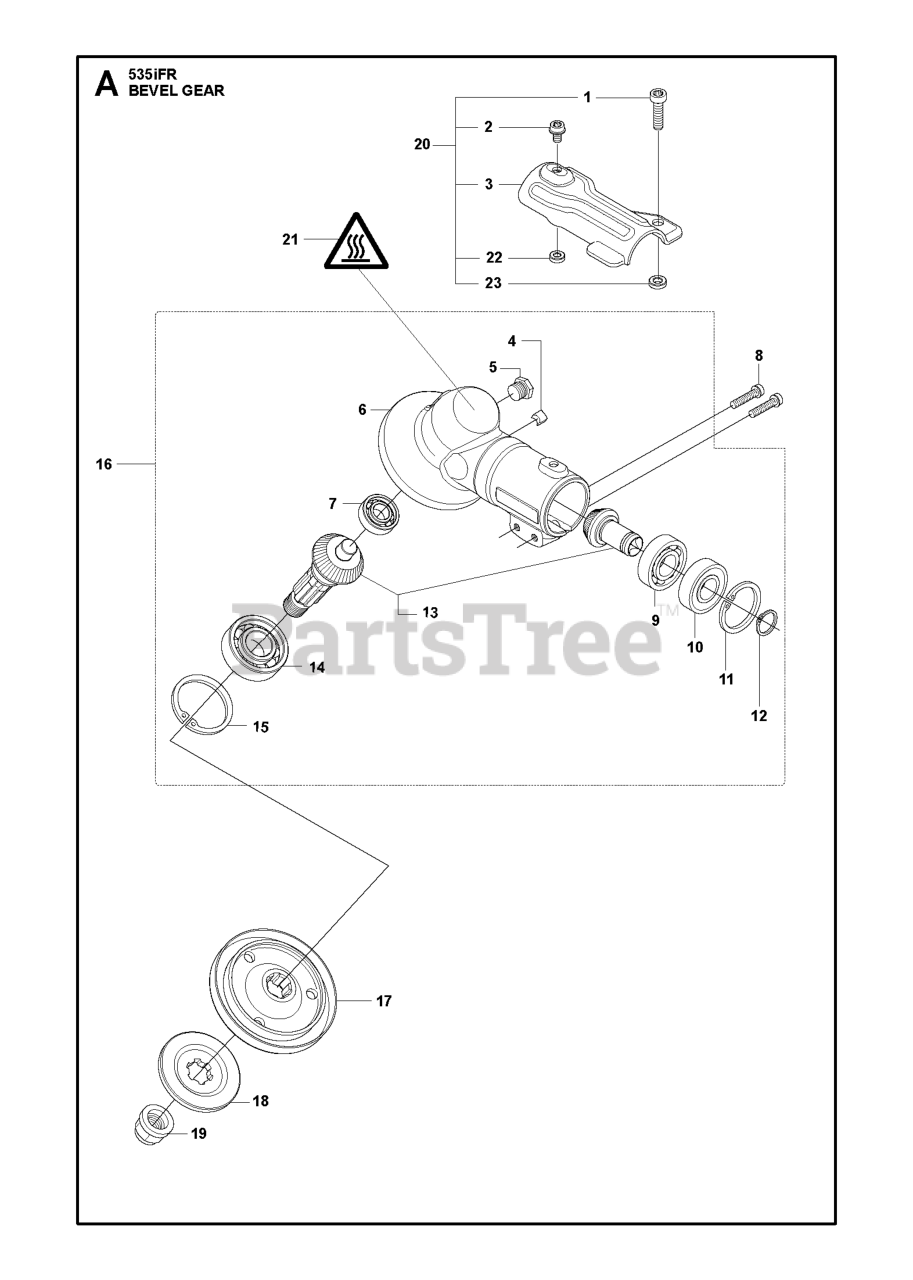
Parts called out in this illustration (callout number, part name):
3	RP HOLDER
5	PLUG
7	BALL BEARING 24X9X1/609ZR
9	BALL BEARING
10	BALL BEARING
11	RETAINING RING SGH 28
12	SEEGER CLIP
13	SPARE PARTS KIT
14	BALL BEARING
15	RETAINING RING
16	GEAR CASE SET
17	CARRIER
22	LOCKING NUT
23	LOCKING NUT M6
